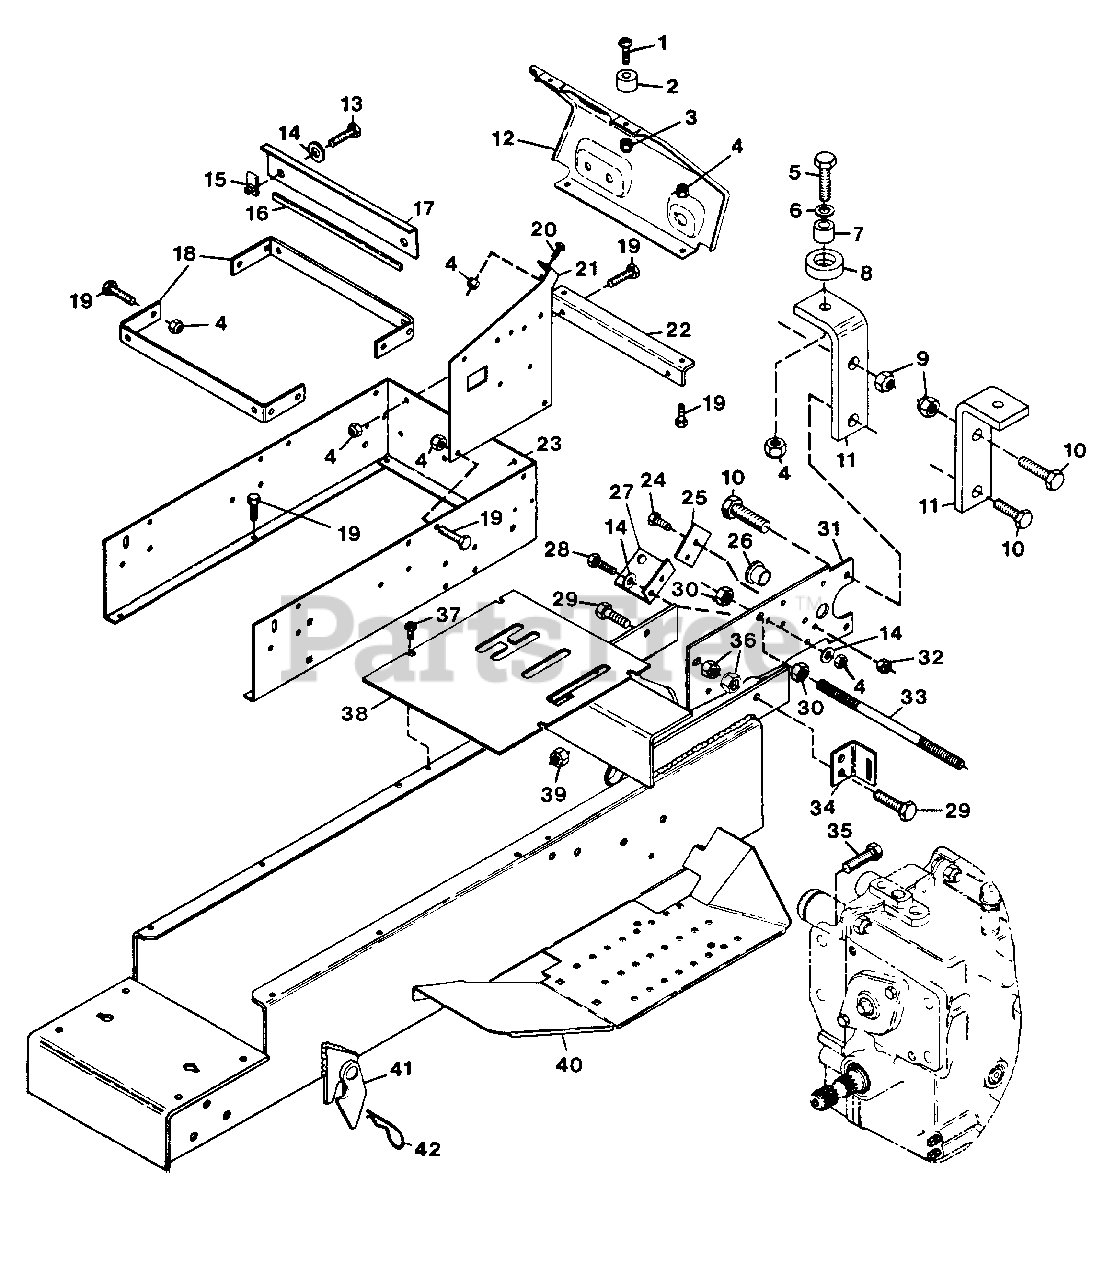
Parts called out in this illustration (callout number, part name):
1	SCREW, MACHINE 6-32X.625 PHD
2	BUMPER
3	NUT, MACHINE LOCK 6-32
4	NUT, LOCK 1/4-20
5	BOLT, HEX 1/4-20X1.25
6	WASHER, FLAT .312X.734X.065
7	BUSH., ST. .265X.375X.250 STL.
8	BUMPER, SEAT
9	NUT, LOCK 1/2-13
10	BOLT, HEX 1/2-13X1.50
11	BRACKET, REAR HITCH
12	PANEL, SILK SCREEN
13	BOLT, HEX 1/4-20X.875
14	WASHER, FLAT .281X.625X.065
15	NUT, RETAINER
16	MOULDING
17	BRACKET, FORWARD TANK
18	BRACKET, FUEL TANK
19	BOLT, HEX 1/4-20X.75
20	SCREW, MACHINE 1/4-20X.75 PHD
21	BRACE, INSTRUMENT PANEL L.H.
21	BRACE, INSTRUMENT PANEL R.H.
22	BRACKET, INSTRUMENT PANEL
23	SUPPORT, INSTRUMENT PANEL
24	BOLT, HEX 5/16-18X.75
25	BRACKET, BUSHING LOCK
26	BUSH., FLG. .764X1.47X.560 NY.
27	BRACKET, INTERLOCK SWITCH
28	BOLT, HEX 1/4-20X1.00
29	BOLT, HEX 3/8-16X1.50
30	NUT, HEX 1/2-13
31	PLATE, FWD-REV MOUNTING
32	NUT, LOCK 5/16-18
33	ROD, FRAME EXTENSION BRACE
34	BRACKET, FENDER HOLD-UP
35	BOLT, HEX 1/2-20X1.50
36	NUT, LOCK 3/8-16
37	SCREW, TAPPING 1/4-20X.625 PHD
38	PLATE, CONTROL COVER SILK SCREEN
39	NUT, RIM
40	WELDMENT, FRAME
41	WELDMENT, MOWER BRACKET R.H.
41	WELDMENT, MOWER BRACKET L.H.
42	PIN, HAIR
